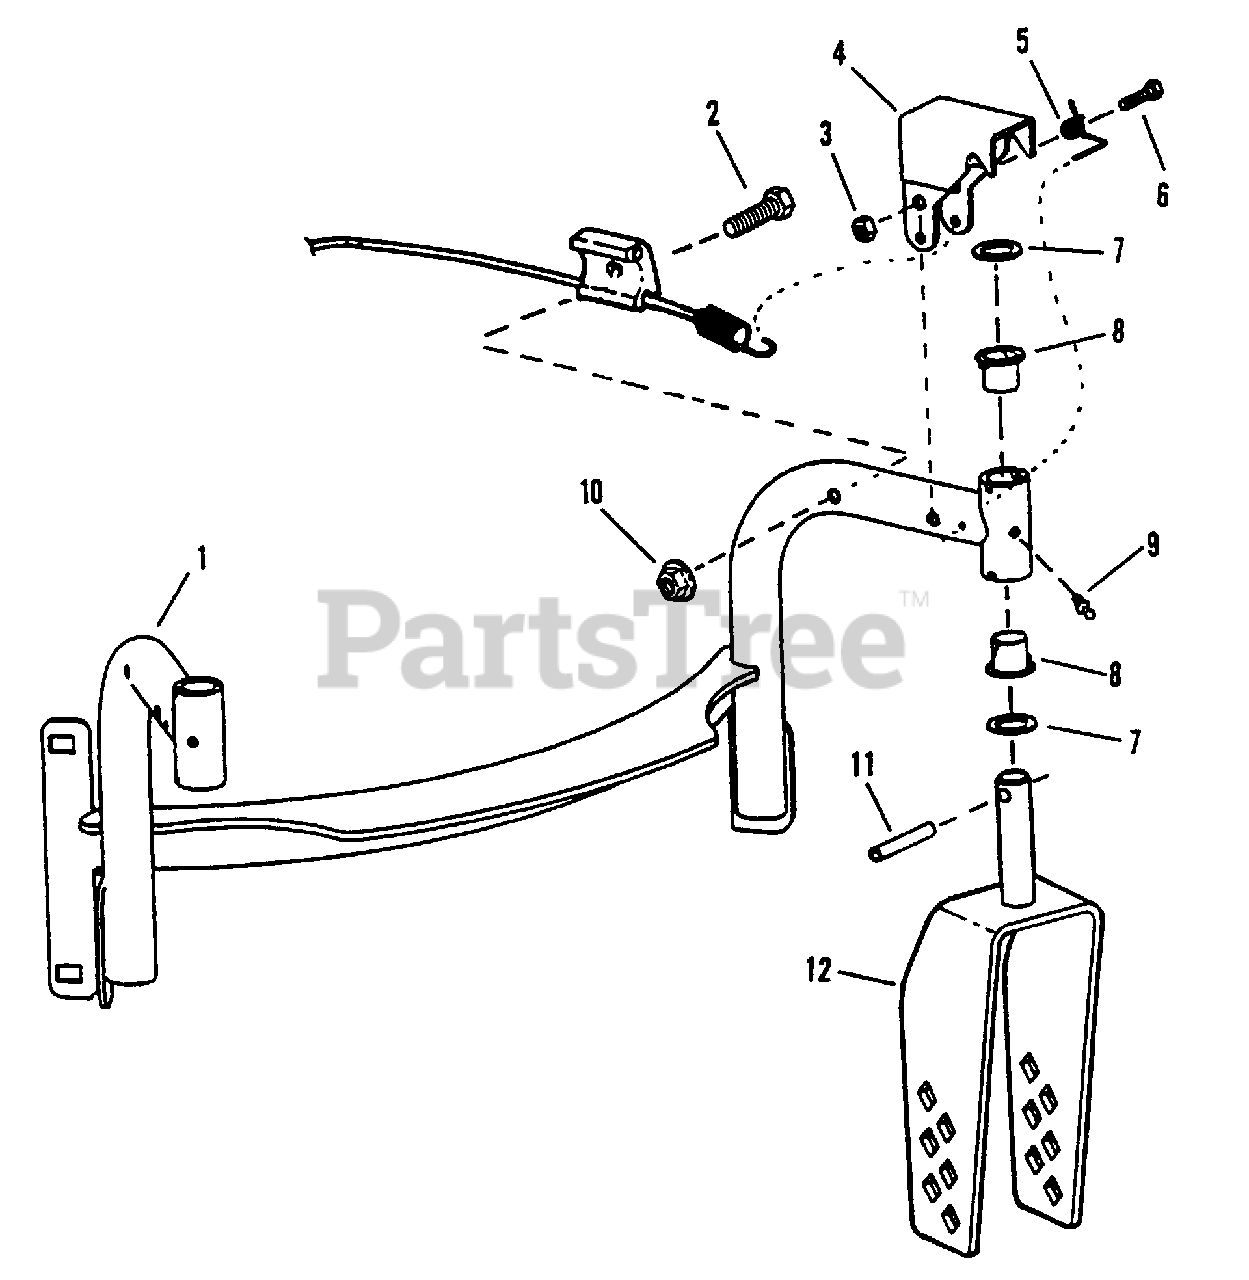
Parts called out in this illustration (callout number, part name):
1	WELDMENT, Front Bracket
2	SCREW, 1/4-20 x 1-1/2" Hex Cap
3	NUT, 1/4-20 Hex Lock
4	BRACKET, Swivel Lock
5	SPRING, Torsion
6	BOLT, 1/4-20 x 2" Hex
7	WASHER, 41/64" Flat
8	BUSHING, 5/8" Nylon
9	LUBE FITTING, Straight (press-fit for .187 dia. Hole)
10	NUT, 1/4-20 Hex Lock
11	PIN, 1/4 x 1-3/4" Roll
12	WELDMENT, L.H. Swivel Bracket
